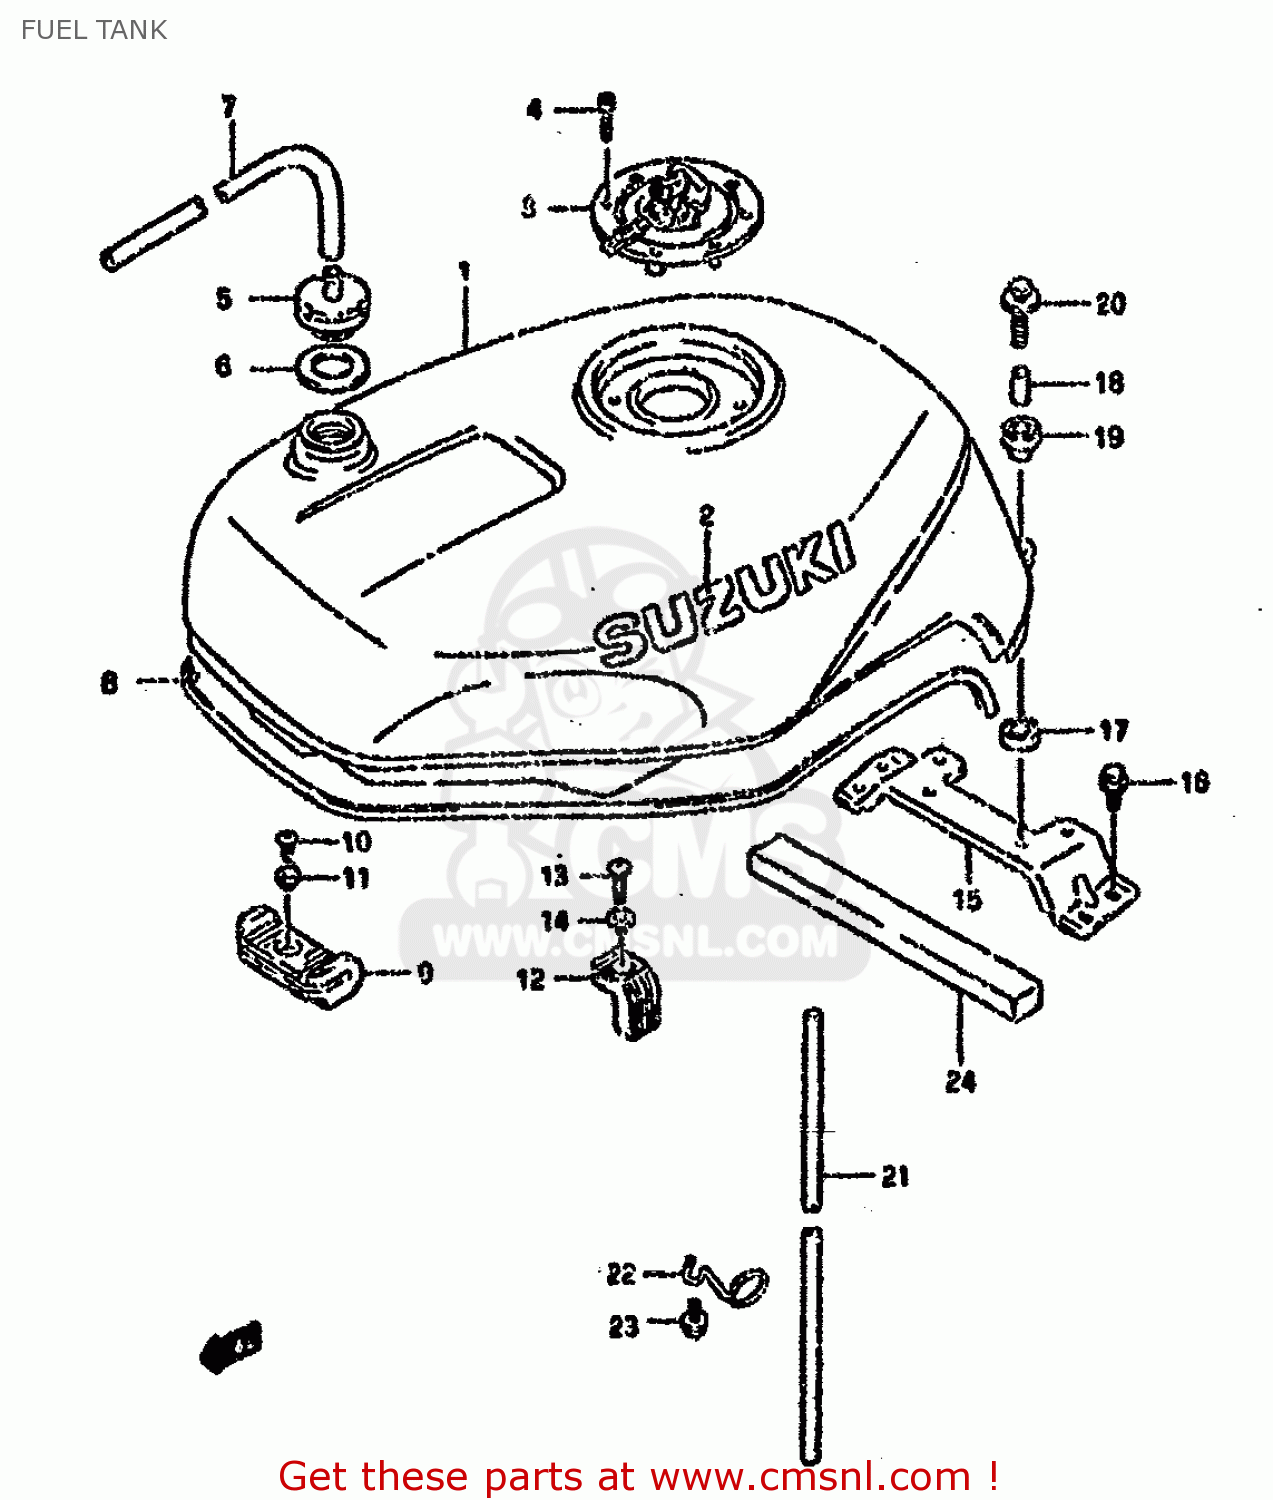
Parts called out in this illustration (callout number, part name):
1	TANK ASSY,FUEL
2	EMBLEM,FUEL TANK
3	CAP SET,FUEL TANK
4	BOLT(5X20)
5	PLUG,FUEL TANK BREATHER
6	GASKET(12.5X20X2.5) (NAS)
7	HOSE(5X8.2X600)
8	MOLDING,FUEL TANK
9	CUSHION,FUEL TANK FR
10	SCREW
11	WASHER
12	CUSHION,TANK SIDE
13	SCREW
14	WASHER
15	BRACKET,FUEL TANK,REAR
16	BOLT
17	CUSHION
18	SPACER
19	CUSHION
20	BOLT
21	HOSE
22	GUIDE,DRAIN HOSE
23	BOLT
24	CUSHION,AIR SEAL
